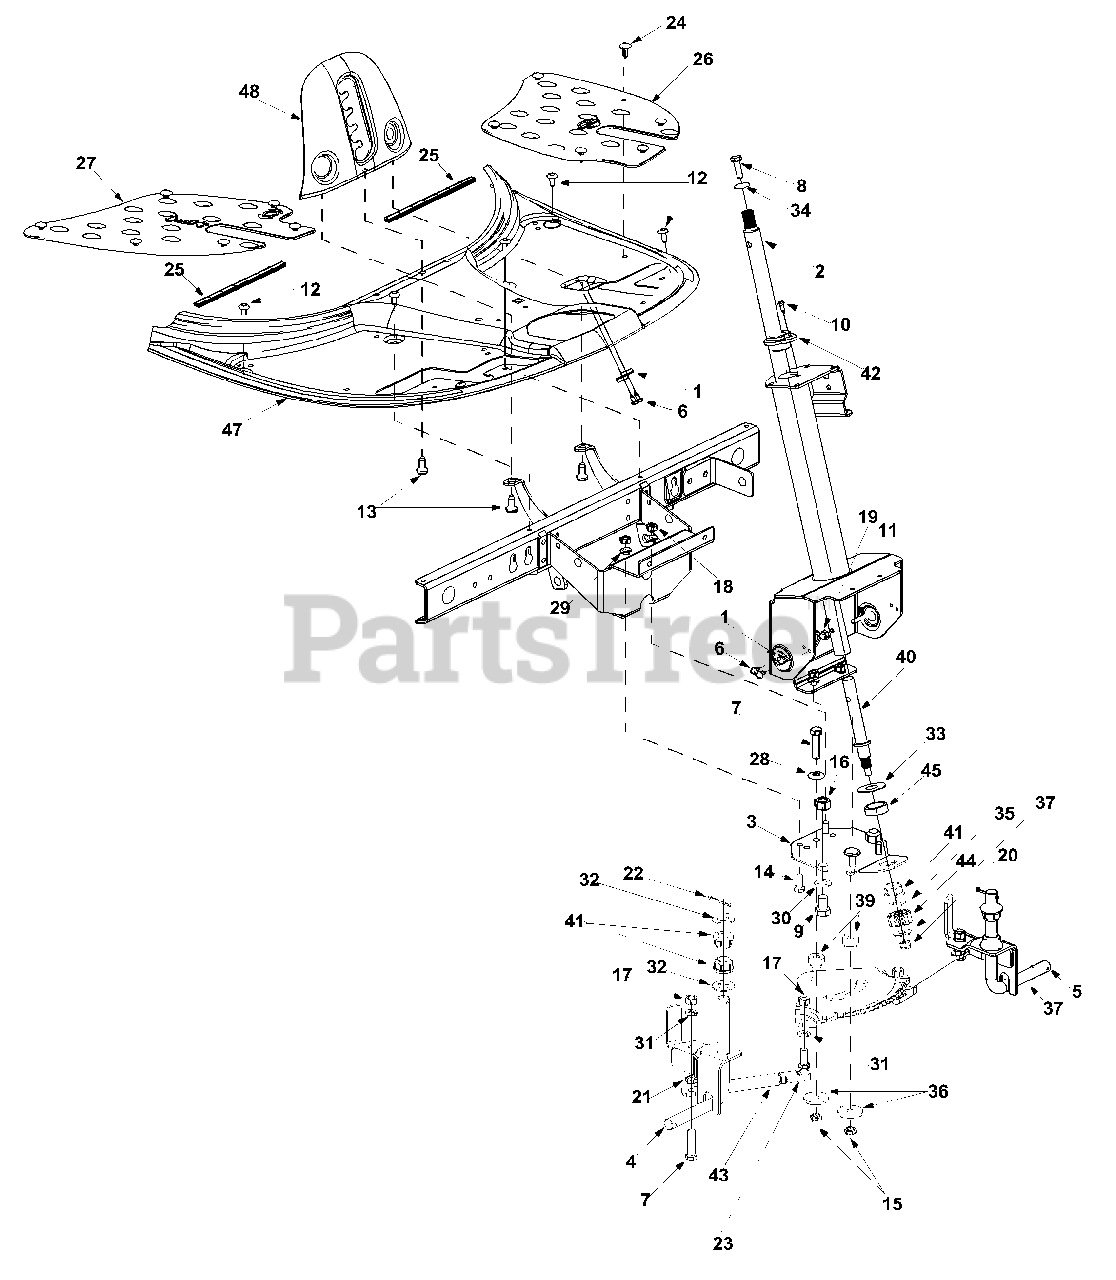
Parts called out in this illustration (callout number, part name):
1	Switch Plate
4	Front Axle Assembly: RH
5	Front Axle Assembly: LH
6	Hex Screw AB
7	Hex Screw 3/8-24 x 1.5" Gr.5 Sp.
8	Lock Screw 5/16-18 x 1.0" Gr.5
9	Hex Screw 1/2-13 x 0.75"
10	Oval C-Sunk Screw #10-16 x 0.625"
11	Hex Screw 1/4-20 x 1.25 Gr.5 Sp.
12	AB Screw 1/4-14 x 0.625"
13	Self-Tapping Screw 5/16-18 x 0.75"
14	Hex Screw 5/16-18 x 0.75"
15	Lock Nut 3/8-24
16	Hex Nut 1/2-13
18	Hex Nut
19	Lock Nut 1/4-20
23	Ball Joint
24	Ratchet Clip
26	Floor Pad: LH
27	Floor Pad: RH
29	Lock Washer
34	Belleville Washer
39	Spacer
40	Steering Adapter
41	Hex Flange Bearing
42	Bearing: Steering Column
44	Pinion Gear
45	Spacer
